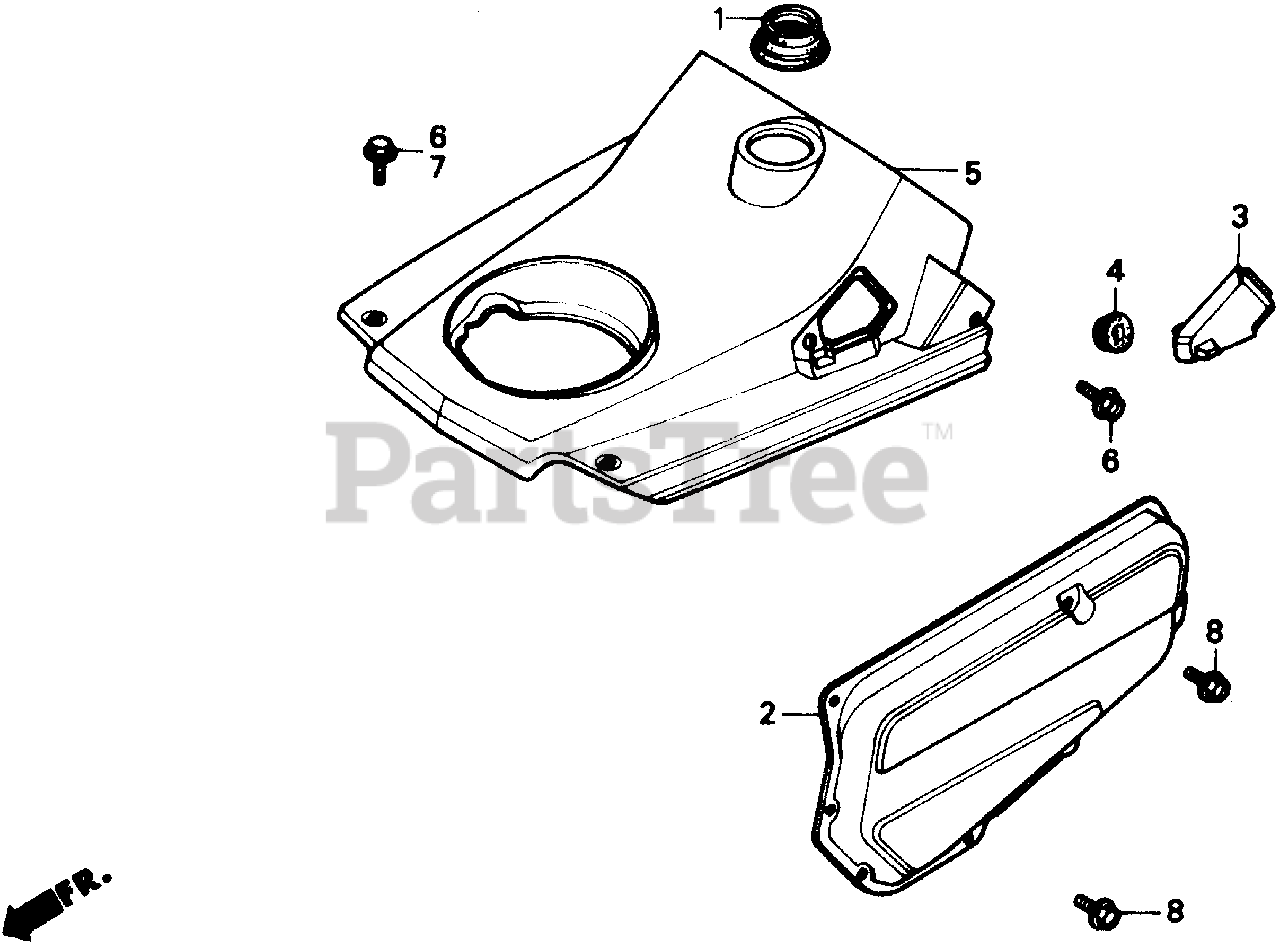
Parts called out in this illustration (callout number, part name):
1	SEAL, FILLER NECK
2	COVER, BELT *NH1* (BLACK)
3	COVER, SPARK PLUG
4	GROMMET, SPARK PLUG COVER (NOT AVAILABLE)
5	COVER, TOP *R8* (BRIGHT RED)
6	BOLT, FLANGE (6MM)
7	BOLT, FLANGE (6X20)
8	BOLT, FLANGE (6X10)
